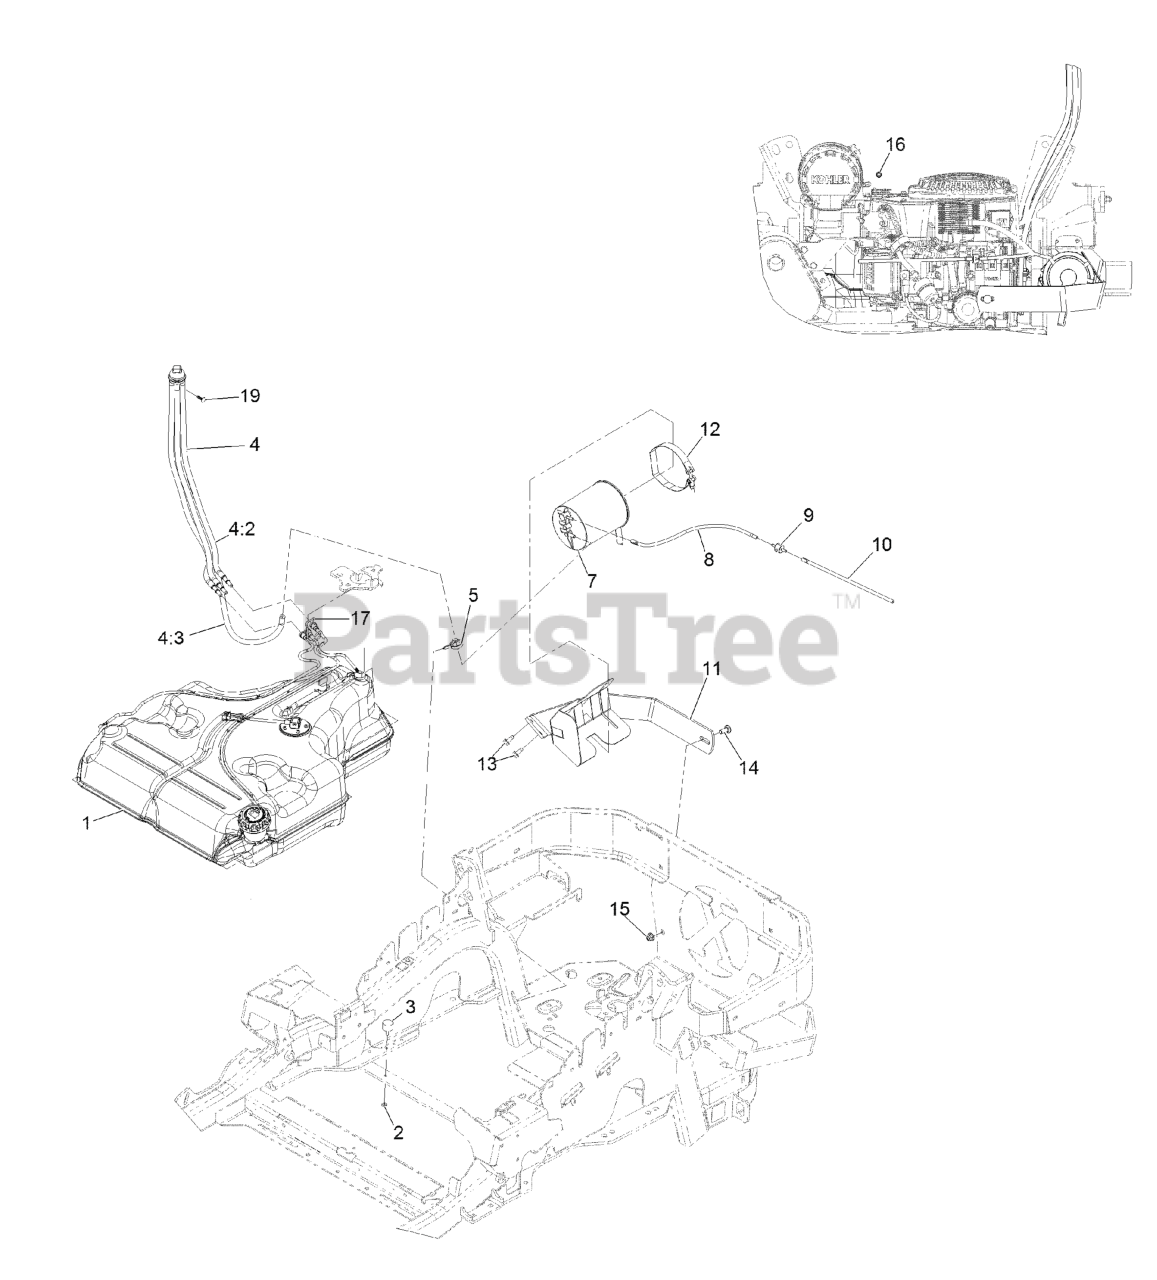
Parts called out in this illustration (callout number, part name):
2	NUT-JAM
4	FUEL MANIFOLD VENT ASM
4:2	HOSE-FUEL
4:3	HOSE-FUEL
5	CLAMP-HOSE
7	CANISTER-CARBON, 1200CC
8	HOSE-VENT, FORMED
9	VALVE-CHECK, VACUUM
10	HOSE-VENT, FORMED
11	MOUNT-CANISTER
12	CLAMP, T-BOLT
13	Screw-HWH 5/16-18 X 3/4 Tf
14	SCREW-CARR
15	NUT-HF, NI
16	PLUG-PORT
17	RETAINER-LINE, VAPOR
19	PLUG-PLASTIC
